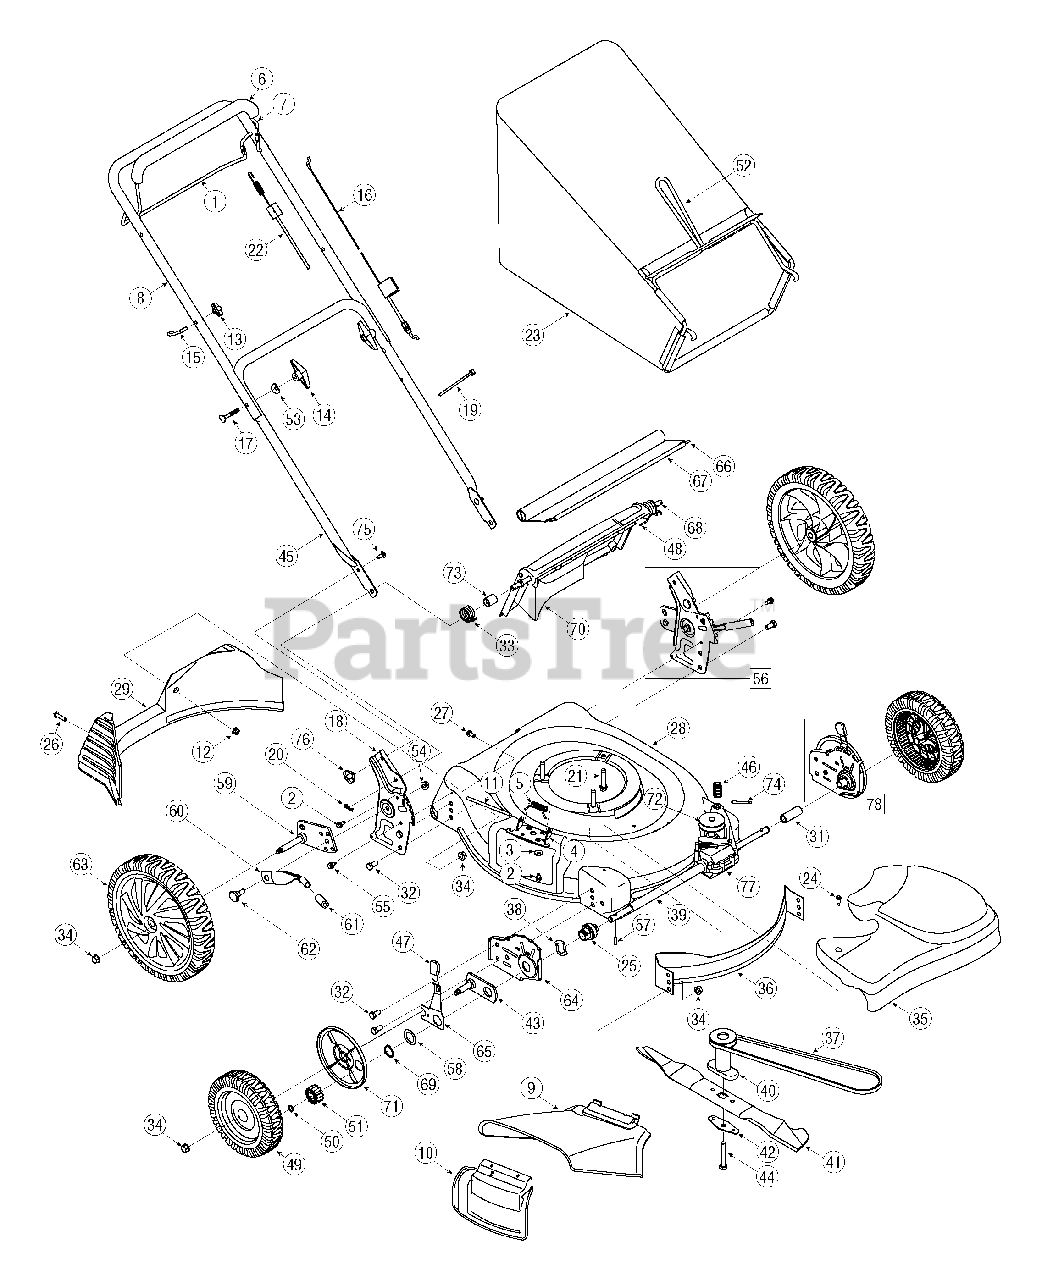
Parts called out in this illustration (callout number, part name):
1	Drive Control
2	TT Screw 1/4-20 x 0.5
3	Bell Washer.265 x 0.75
4	Deflector Chute Adapter
5	Torsion Spring
6	Deluxe Bail Cover
9	Chute Deflector
10	Mulch Plug Complete
11	Hinge Pin
12	Flange Lock Nut, 1/4-20
13	Handle Knob
14	Handle Knob
15	Eye Bolt
16	Control Cable - 40.75"
17	Carriage Bolt 5/16-18 x 2.0
18	Handle Bracket - RH
19	Cable Tie
20	Cotter Pin
21	Self-Tapping Sems Screw
22	Drive Cable - 50.50"
23	Grassbag Assembly
24	Shoulder Screw # 12 -24
25	Front Bearing Assembly
26	Screw, 1/4-15 x 1.25
27	Screw, 1/4-20 x.500
31	Slev. Spacer 2.1" Lg.
32	Hex Screw 3/8-16 x.75
33	Torsion Spring - RH
34	Flange Lock Nut 3/8-16
35	Transmission Cover (Gray)
36	Front Baffle
37	V-Belt
38	Wave Washer
39	Sleeve Spacer 9.04" Lg.
40	Blade Adapter w/ Pulley
41	21" Mulching Blade
42	Blade Bell Support
43	Pivot Plate Assembly
44	Hex Screw 3/8-24 x 2.50
46	Belt Tension Spring
47	Adjustment Knob
48	Torsion Spring - LH
49	Front Wheel 8 x 2.125
50	Snap Ring
51	Gear 14T RH FWD
53	Saddle Washer
54	Hex Flange Lock Nut 3/8-16
55	TT Scr. w/Washer 1/4-20 x.625
56	Handle Bracket Assembly - LH
57	Dowel Pin
58	Washer
59	Pivot Arm Assembly - RH
60	Rear Spring Lever
61	Foam Grip
62	Shoulder Scr.500 Dia. x.434
63	Rear Wheel, 12 x 2.125
66	Wire
67	Rear Trailing Shield
68	Pivot Rod
69	Snap Ring
70	Rear Discharge Door
71	Wheel Dust Cap
72	Input Pulley
73	Spacer.375 x.50 x 1.02" Lg.
74	Roll Pin
75	Carriage Bolt 1/4-20
76	Wing Nut
77	Transmission Assembly
78	Height Adjustment Assembly - RH
